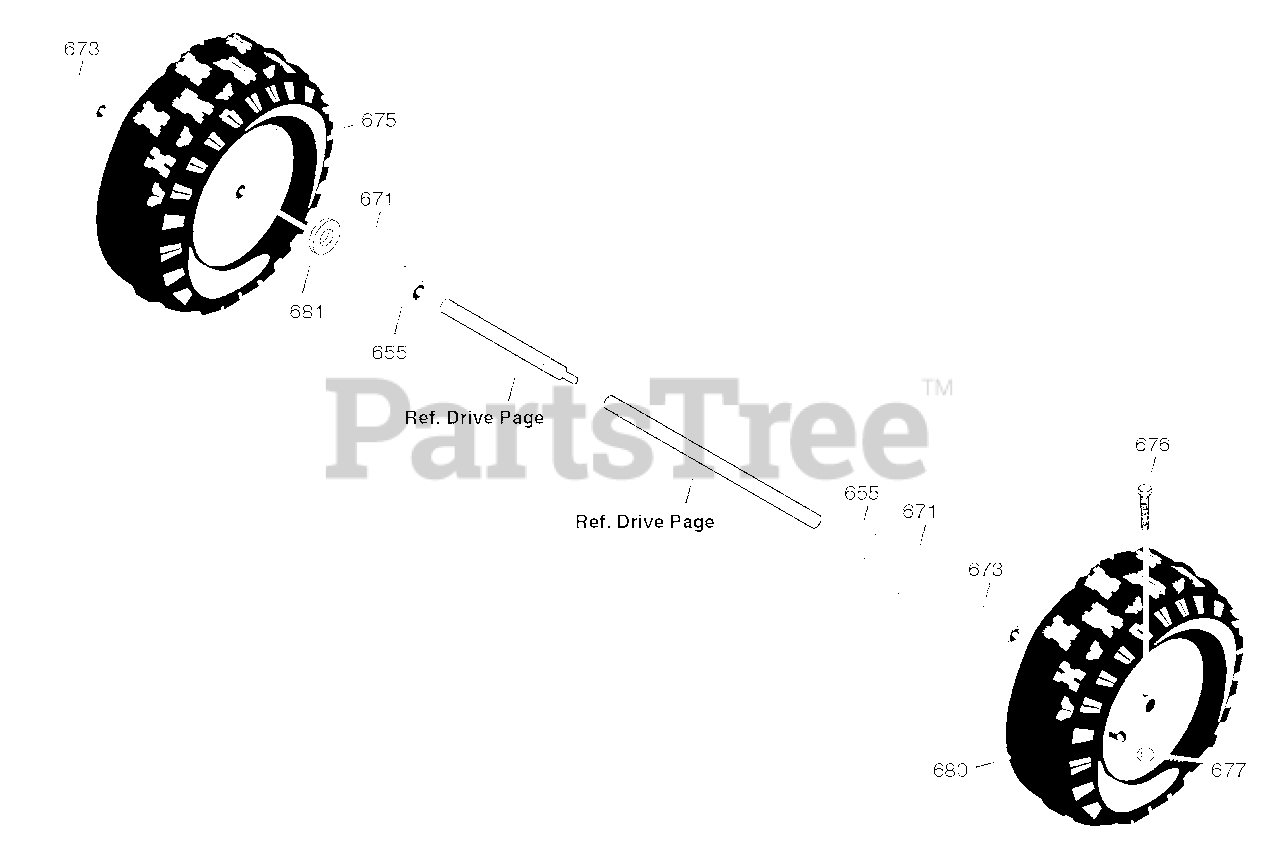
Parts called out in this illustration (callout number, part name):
655	BEARING, AXLE
671	FLATWASHER
673	BUSHING, WHEEL
675	TIRE & RIM, LEFT
676	SCREW, 1/4-20X1.75 HH
677	NUT, 1/4-20 HEX NYLOCK
680	TIRE & RIM, RIGHT
681	RETAINER
